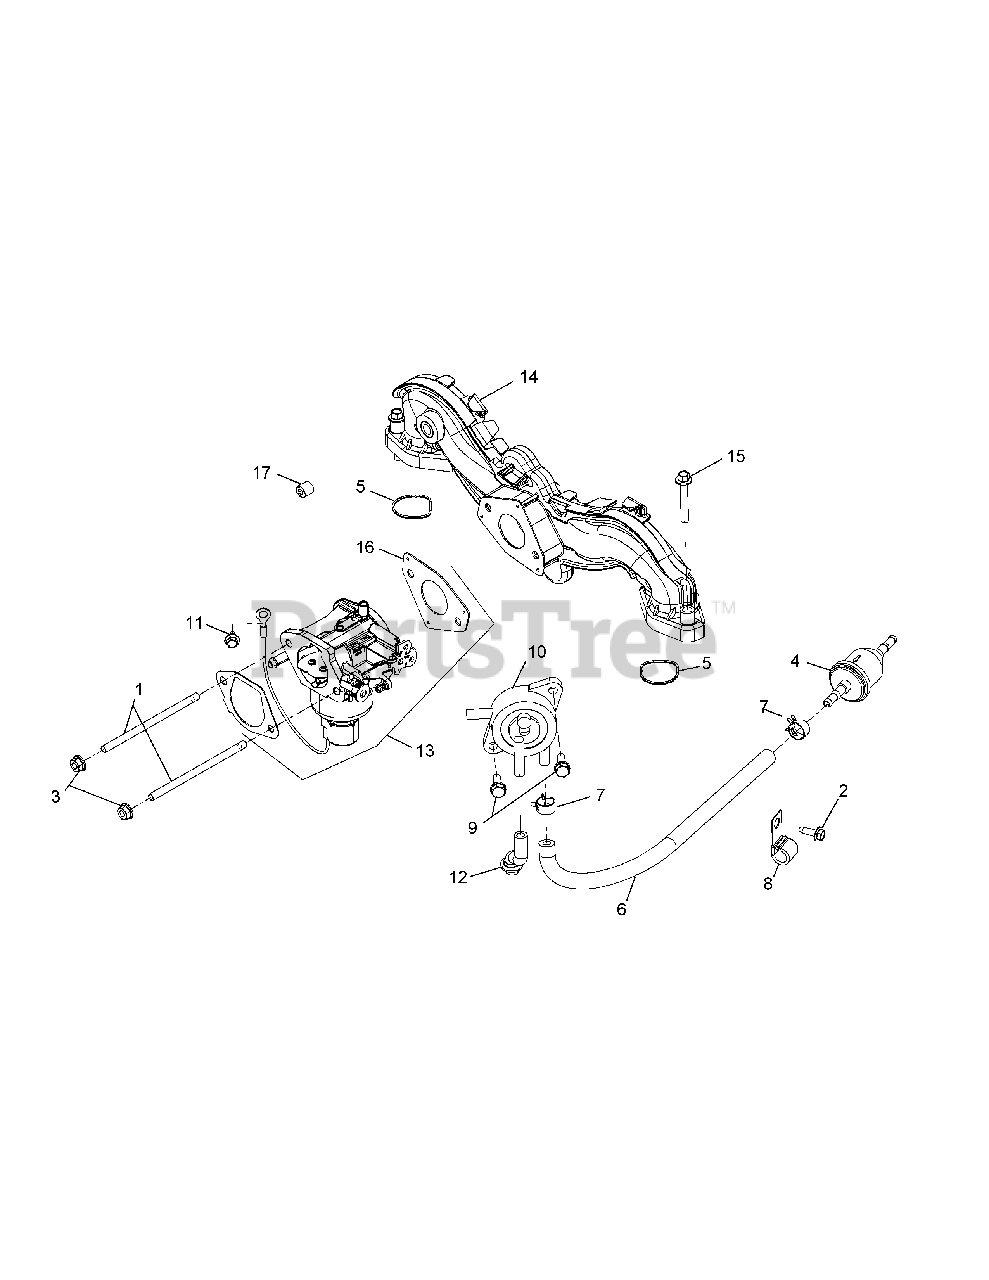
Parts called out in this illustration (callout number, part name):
2	Thread Forming Screw
3	Flange Nut, M6 x 1.0
5	Intake Port O-Ring
6	Fuel Line, 24"
7	Spring Hose Clamp
9	Tap Screw, M6 x 1.7 x 18
11	Thread Forming Screw
12	Pulse Pump Hose
13	Carburator Kit
14	Intake Manifold Kit
15	Flange Screw, M6 x 1.0 x 40
16	Carburetor Gasket
17	Pipe Plug, 1/8
